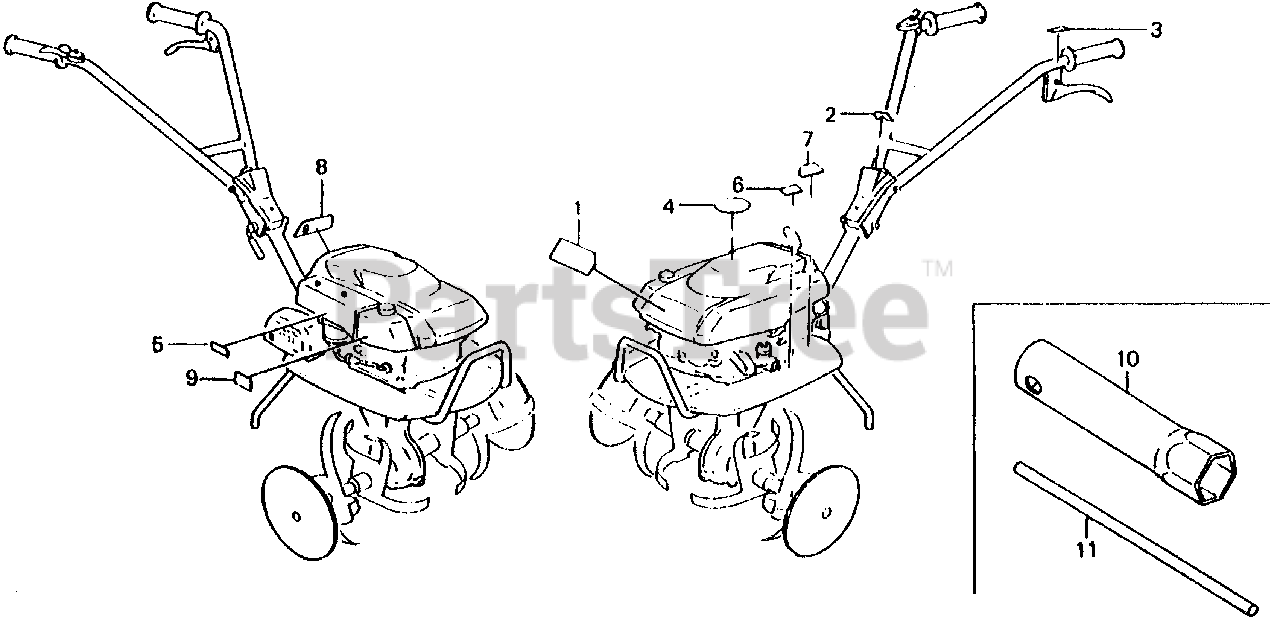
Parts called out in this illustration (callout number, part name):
1	MARK, TOP (NOT AVAILABLE)
2	MARK, SWITCH
3	CAUTION, CLUTCH LEVER (ENGLISH)
4	LABEL, CAUTION (ENGLISH) (NOT AVAILABLE)
5	MARK, CHOKE (ENGLISH) (NOT AVAILABLE)
6	MARK, ENGINE OIL CAUTION
7	MARK, TRANSMISSION OIL CAUTION
8	MARK, STARTING
9	LABEL, CAUTION (NOT AVAILABLE)
10	WRENCH, SPARK PLUG (NOT AVAILABLE)
11	BAR A, HANDLE
